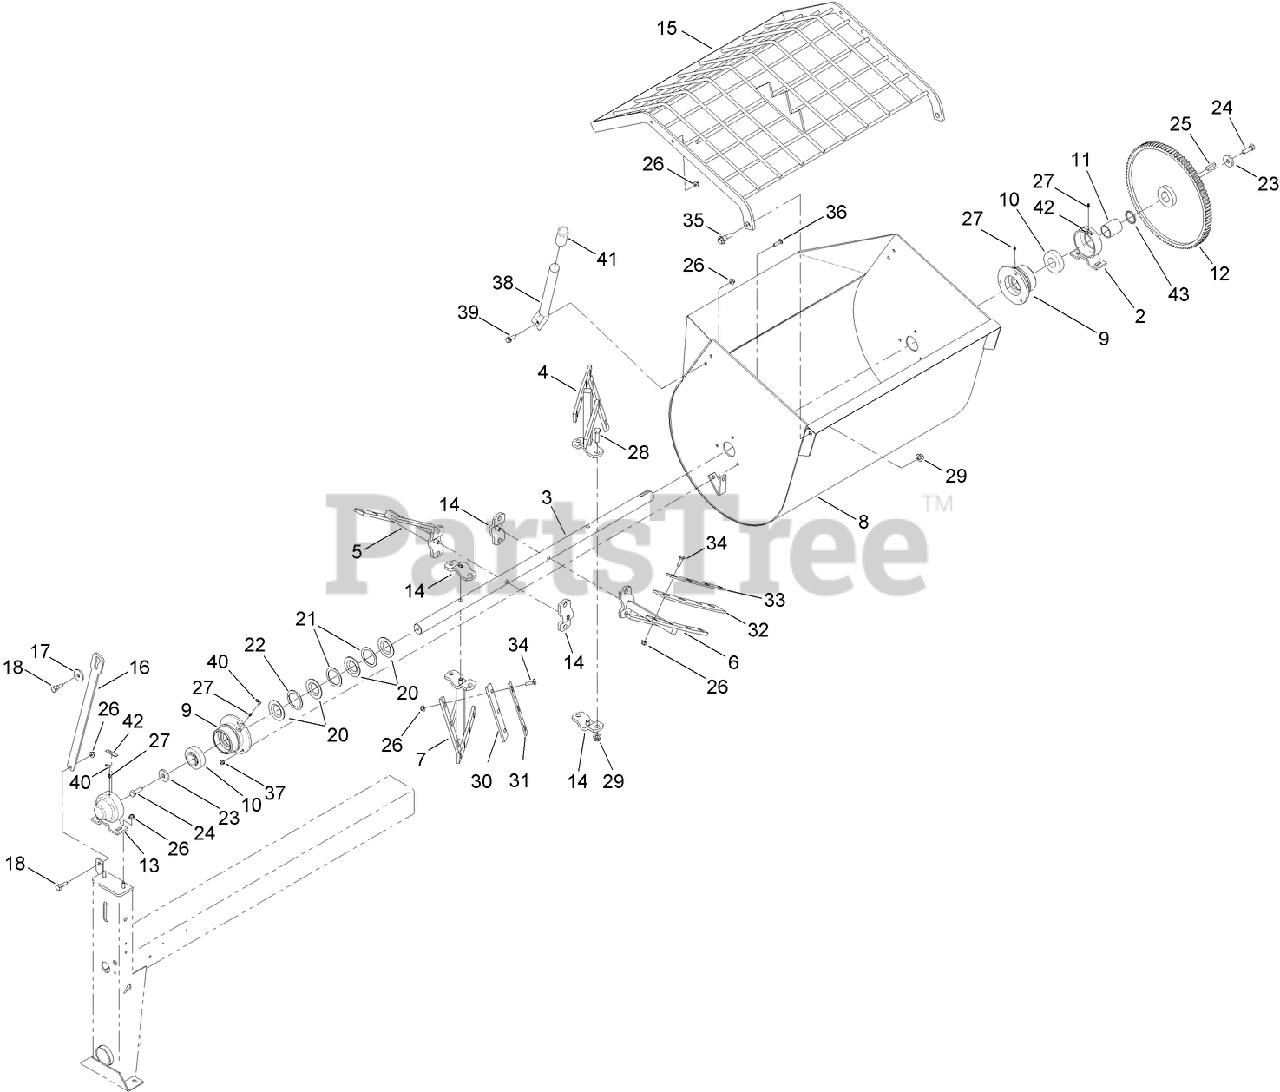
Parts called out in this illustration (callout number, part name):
2	TRUNNION
3	SHAFT-DRUM
9	HOUSING-BEARING
10	BEARING-BALL
11	SPACER-SHAFT, DRUM
12	GEAR-94 TEETH
13	TRUNNION-CAPPED
15	GUARD-DRUM
16	BAR-GUARD, LIFT
17	Washer-Thrust
18	BOLT-SHOULDER
20	SEAL-DRUM
21	WASHER-FLAT
22	WASHER-SPLIT
23	WASHER-FLAT
24	SCREW-HH
25	KEY-SQUARE
26	NUT-HF, NI
27	FITTING-GREASE
28	SCREW-HH
29	NUT-LOCK
30	BLADE-RUBBER, SHORT
31	BAR-BACKER, SHORT
32	BLADE-RUBBER, LONG
33	BAR-BACKER, LONG
34	BOLT-CARR
35	SCREW-SHOULDER, HHF
36	SCREW-CARR
37	NUT-HF, NI
38	HANDLE-DUMP
39	SCREW-HHF
40	CAP-PLUG
41	GRIP-HAND
42	DECAL-GREASE
43	SPACER-SHAFT, DRUM
